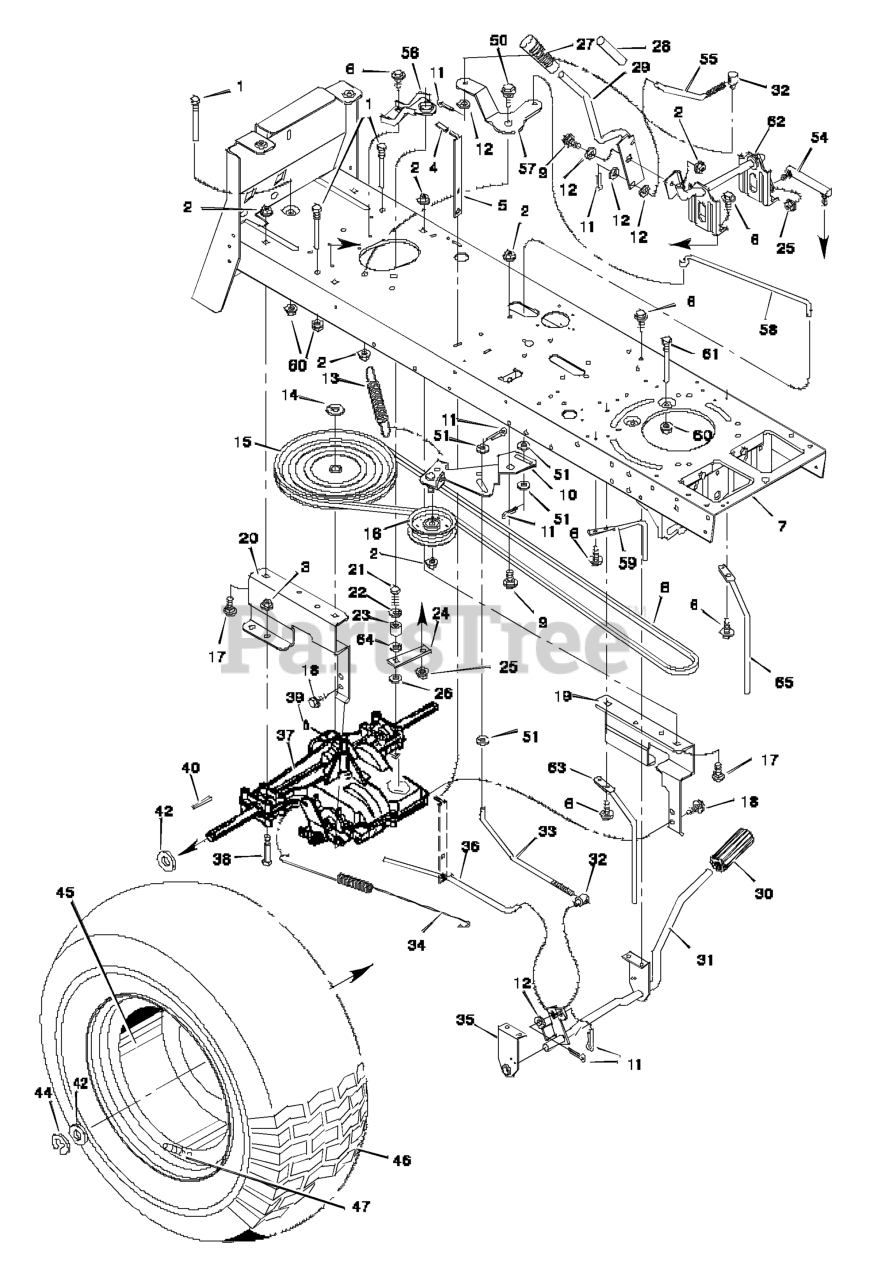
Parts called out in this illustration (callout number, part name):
1	Guide, Belt
2	Locknut, Flange
3	Locknut, Flange
5	Lever, Parking Brake
8	Belt, Motion Drive
9	Bolt, Shoulder
10	Bracket Assembly, Idler
11	Pin, Cotter
12	Washer
13	Spring, Drive Extension
14	Ring, Retainer
15	Pulley, Motion Drive
16	Pulley, Backside Idler
17	Bolt, Carriage
19	Bracket, Left Transaxle
20	Bracket, Right Transaxle
21	Bolt, Hex
22	Lockwasher
23	Pilot, Support
24	Yoke, Shift Lever
25	Locknut
28	Grip, Inner
29	Lever, Shift
30	Pedal, Clutch/Brake
31	Lever Assembly, Pedal
32	Nut, Adjustable
33	Rod, Clutch
34	Spring, Brake Extension
35	Bracket, Pedal Support
36	Rod, Brake Latch
37	Transaxle, Peerless **
38	Bolt, Hex
39	Key, Woodruff No. 9
40	Key, Square
42	WASHER, 1-1.3 16G FLT
45	Wheel & Tire Assembly
46	Tire Only *
47	Valve Stem
50	Bolt, Shoulder
51	Washer
52	Washer
54	Link, Shifter
55	Link, Clutch
56	Bracket, Support
57	Bracket, Pivot
58	Rod, Clutch
59	Guide, Belt
60	Nut, Flange
61	Guide, Belt
62	Shifter Assembly
63	Guide, Belt
65	Guide, Belt
